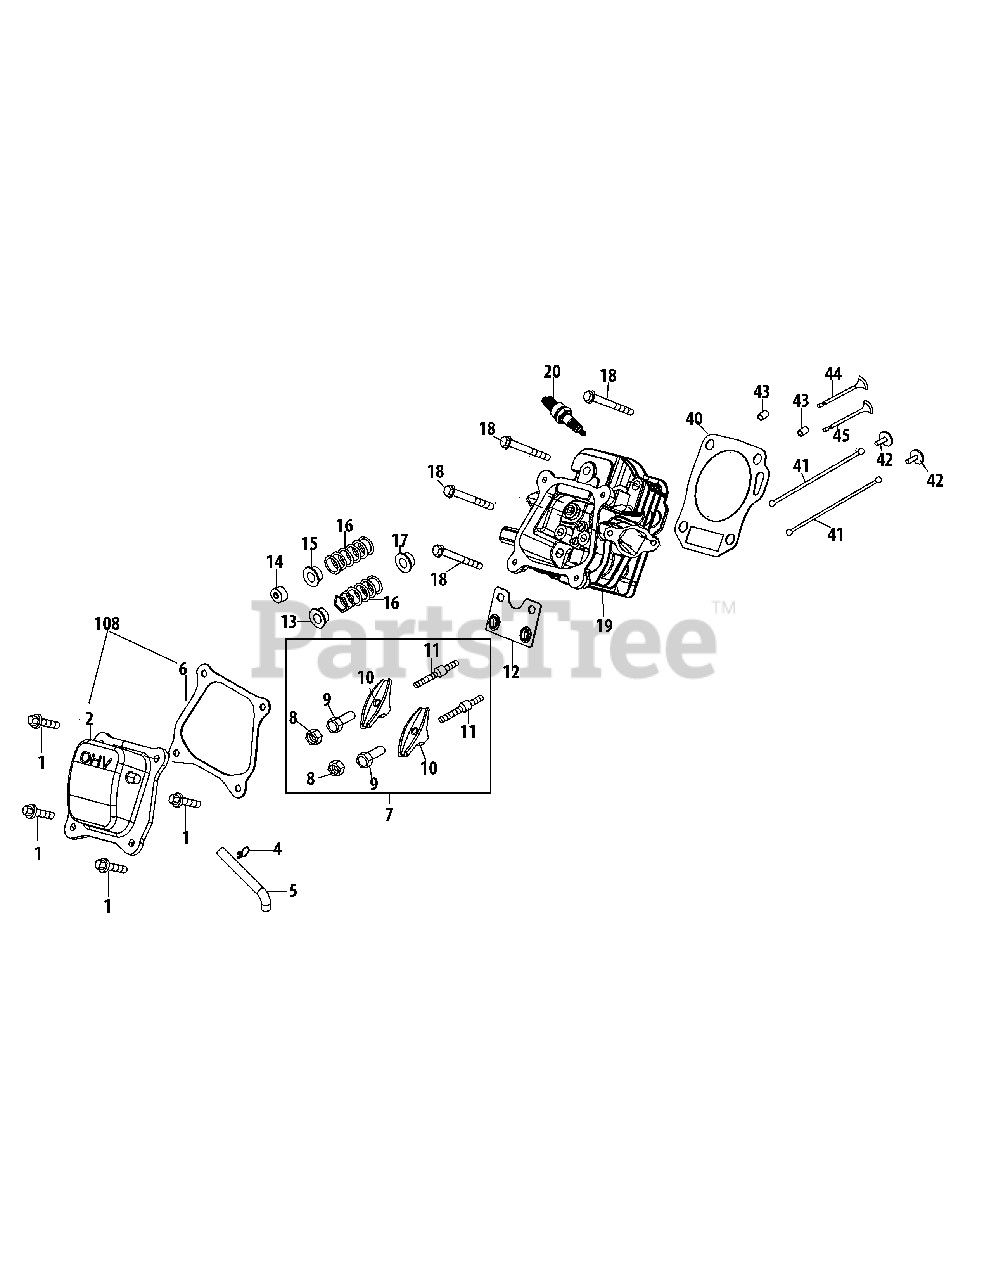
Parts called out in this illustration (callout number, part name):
1	Bolt M6×16
2	Valve Cover
4	Breather Hose Clamp
5	Breather Hose
6	Valve Cover Gasket
7	Rocker Arm Assembly
8	Nut, Pivot Locking
9	Adjusting Nut, Valve
10	Rocker Arm
11	Bolt, Pivot
12	Push Rod Guide
13	Retainer, In.Valve Spring
14	Adjuster, Ex. Valve
15	Retainer, Ex. Valve Spring
16	Valve Spring
17	Intake Valve Seal
18	Bolt M8×55
19	Cylinder Head
20	Spark Plug
40	Gasket, Cylinder Head
41	Push Rod Kit
43	Dowel Pin 10×16
108	Valve Cover Kit
